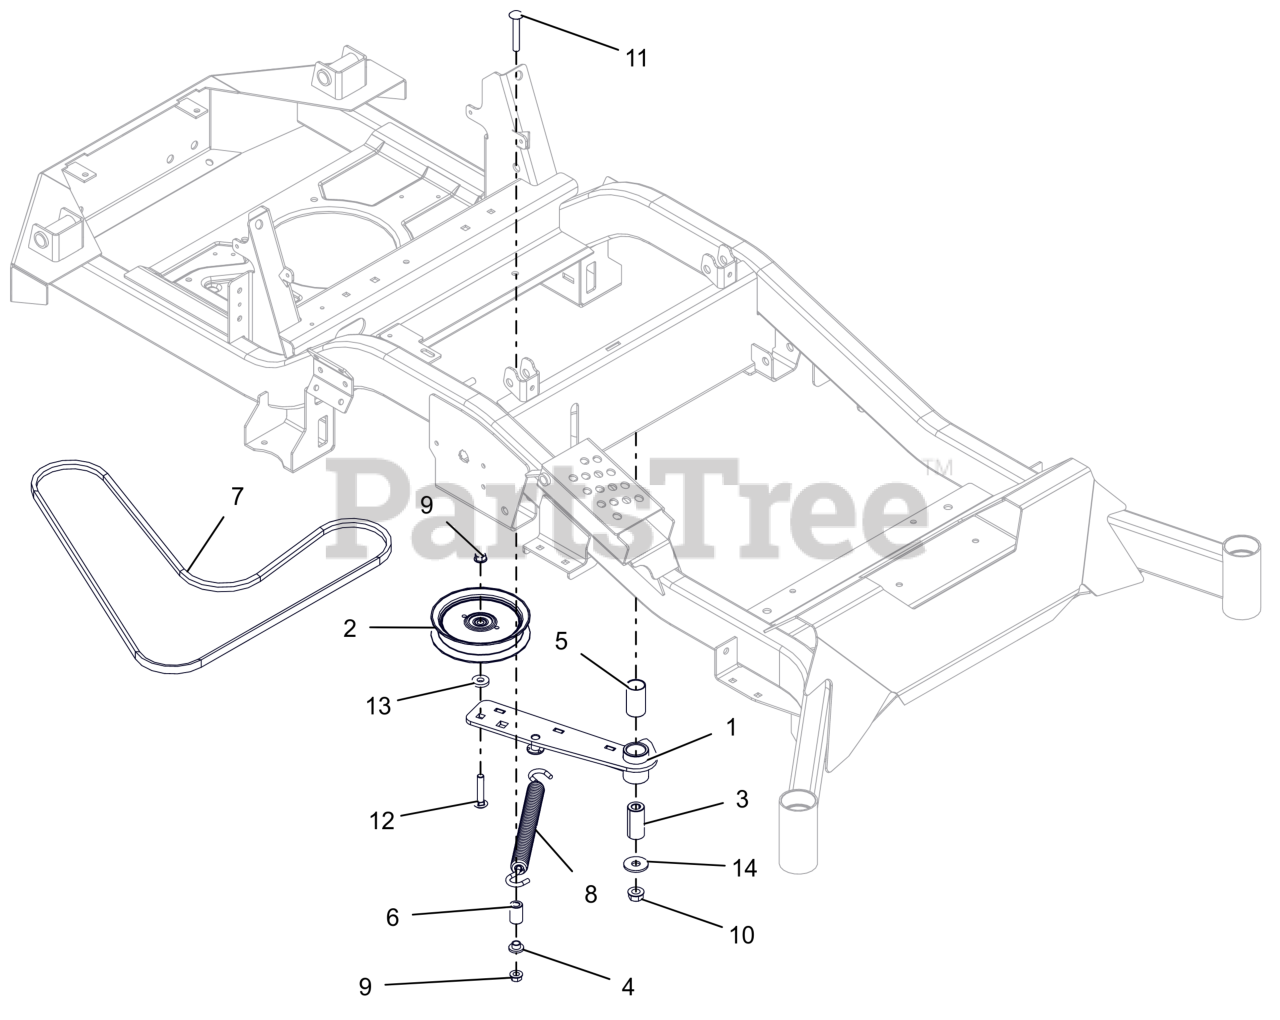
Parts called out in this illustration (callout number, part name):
1	WLDMT, HYDRO DRIVE IDLER ARM (BLACK)
2	IDLER, FLAT 5.00"
3	BSHG, SPCR .502X.997X2.03 PM
4	BSHG-FLG .385X.500X.875X.406
5	BSHG, 1.00X1.125X1.937
6	BUSHING, SLV .380X.750X1.190
7	V-BELT, 4L-WRAPPED
8	SPRING, EXTENSION
9	NUT-LK-TOP-FLG .38-16 ZC120
10	NUT-LK-TOP-FLG .500-13 GF ZCC
11	BLT, RHSSN.38-16X2.50 G5 ZCC
12	BLT, RHSN .38-16X2.00 G5 ZCC
13	WSHR, FLT .406X1.00X.188 ZCC
14	WSHR-FL-STL.511X1.44X.125ZC120
